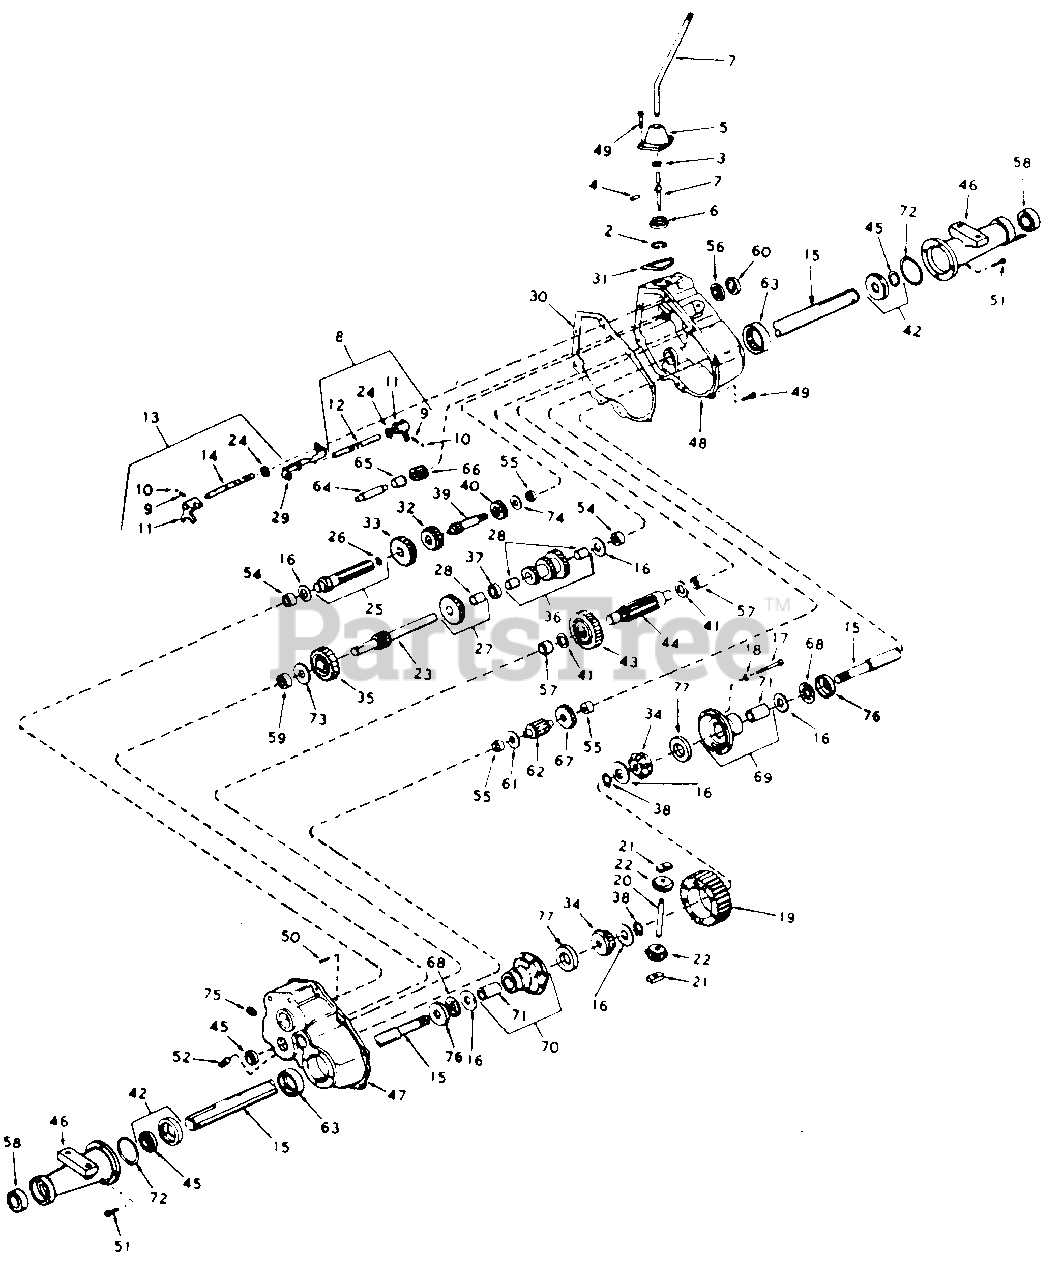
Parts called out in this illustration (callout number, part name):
2	Ring: Snap
3	Ring: Quad
4	Pin: Roll
5	Housing: Shift Lever
6	Keeper: Shift Lever
7	Lever: Shift
8	Rod Ass'y.: Shift
9	Spring: Shif t Fork
10	Ball. Steel
11	Fork: Shifter
12	Rod: Shifter
13	Rod Ass'y.: Shift
14	Rod: Shifter
15	Axle (18-11/32" Long)
16	Washer: Thrust
17	Scr.: Hex Hd.: 1/4-20 x 2-1/2
18	Lock Washer: 1/4"
19	Gear: Ring
20	Pin: Drive
21	Block: Drive
22	Pinion: Bevel
23	Shaft and Gear: Brake
24	Ring: Snap
25	Shaft and Bearing Ass'y.: Pinion
26	Bearing: Needle
27	Gear Cluster Ass'y.
28	Bushing
29	Stop: Shifter
30	Gasket: Case and Cover
31	Gasket: Shifter Lever Housing
32	Gear: Shifting
33	Gear: Shifting
34	Gear: Bevel
35	Gear: Idler
36	Gear Cluster Ass'y.
37	Spacer
38	Ring: Snap
39	Shaft: Input
40	Spur Gear: Input Shaft
41	Washer: Thrust
42	Seal and Retainer Ass'y.: Oil
43	Gear: Output
44	Pinion: Output
45	Seal: Oil
46	Housing: Axle
47	Cover Ass'y.: Transaxle
48	Case Ass'y.: Transaxle
49	Screw: Socket Hd.: 1/4-20 x 3/4
50	Pin: Dowel
51	Screw: Hex Hd. Sems: 5/16-18 x 1
52	Plug: Magnetic Drain
54	Bearing: Needle
55	Bearing: Needle
56	Bearing: Ball
57	Bearing: Needle
58	Bearing: Ball
59	Bearing: Needle
60	Seal: Oil
61	Washer
62	Shaft and Pinion
63	Bearing: Needle
64	Shaft: Reverse Idler
65	Spacer: Reverse Idler
66	Idler: Reverse
67	Spur Gear (22 Teeth)
68	Bearing: Thrust
69	Carrier Ass'y.: Differential
70	Carrier Ass'y: Differential
71	Bushing
72	Seal: Square Cut
73	Washer: Thrust
74	Washer: Thrust
75	Plug: Pipe
76	Race: Thrust
77	Washer
